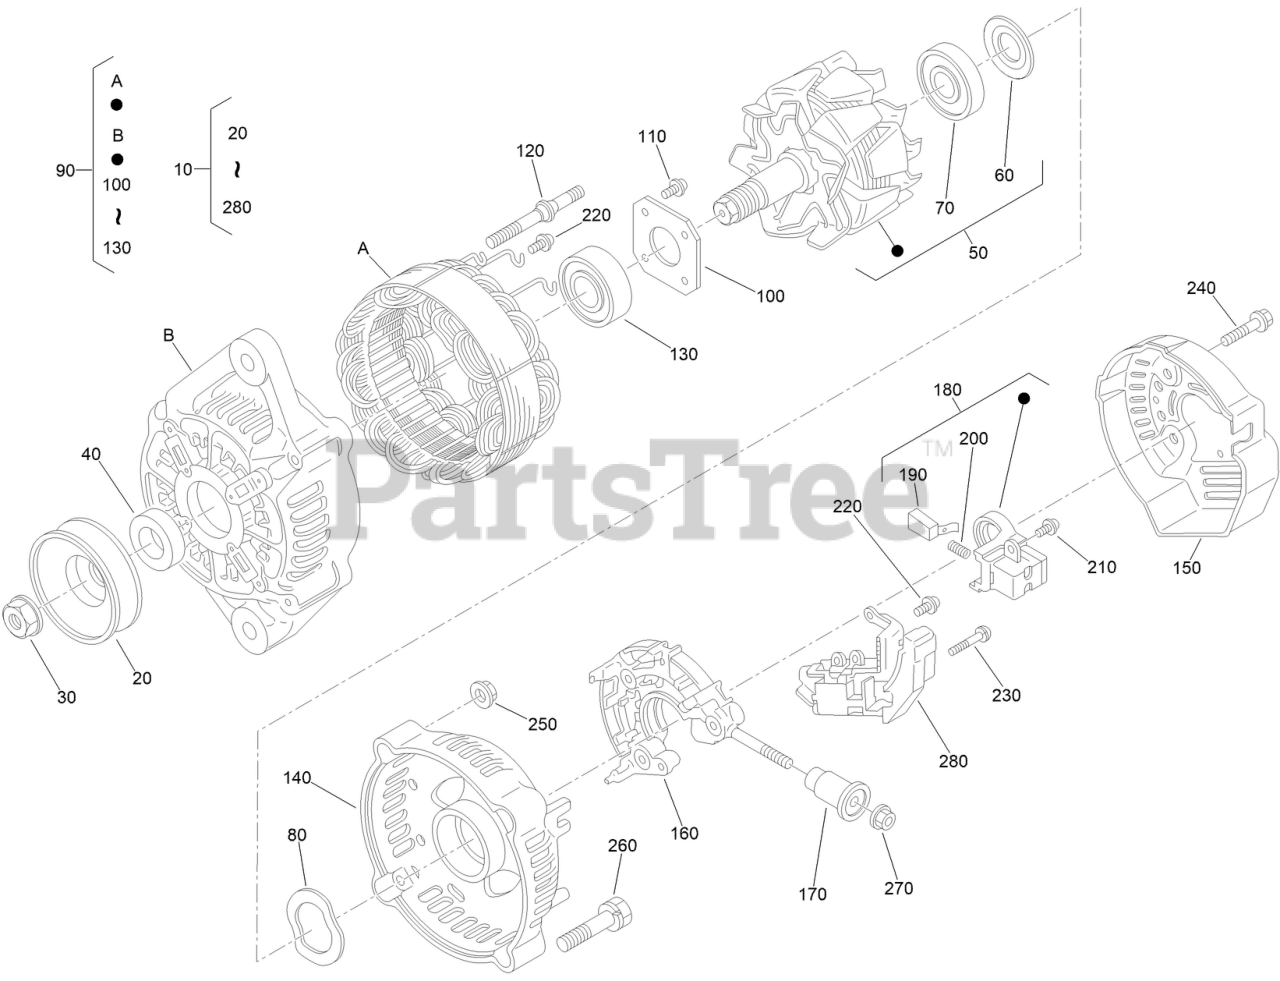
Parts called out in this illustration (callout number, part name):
10	ALTERNATOR ASM
20	PULLEY-DYNAMO
40	COLLAR
50	ROTOR ASM
60	COVER-BEARING
70	BEARING-BALL
80	WASHER-THRUST
90	DRIVE END FRAME ASM
100	PLATE-RETAINER
110	SCREW-HEAD, ROUND
120	BOLT-THROUGH
130	BEARING
140	FRAME-END
150	COVER-END
160	RECTIFIER ASM
170	INSULATION-BRUSH
180	BRUSH HOLDER ASM
190	BRUSH
200	SPRING-BRUSH
210	SCREW-HEAD, ROUND
220	SCREW-HEAD, ROUND
230	SCREW-HEAD, ROUND
280	REGULATOR ASM
